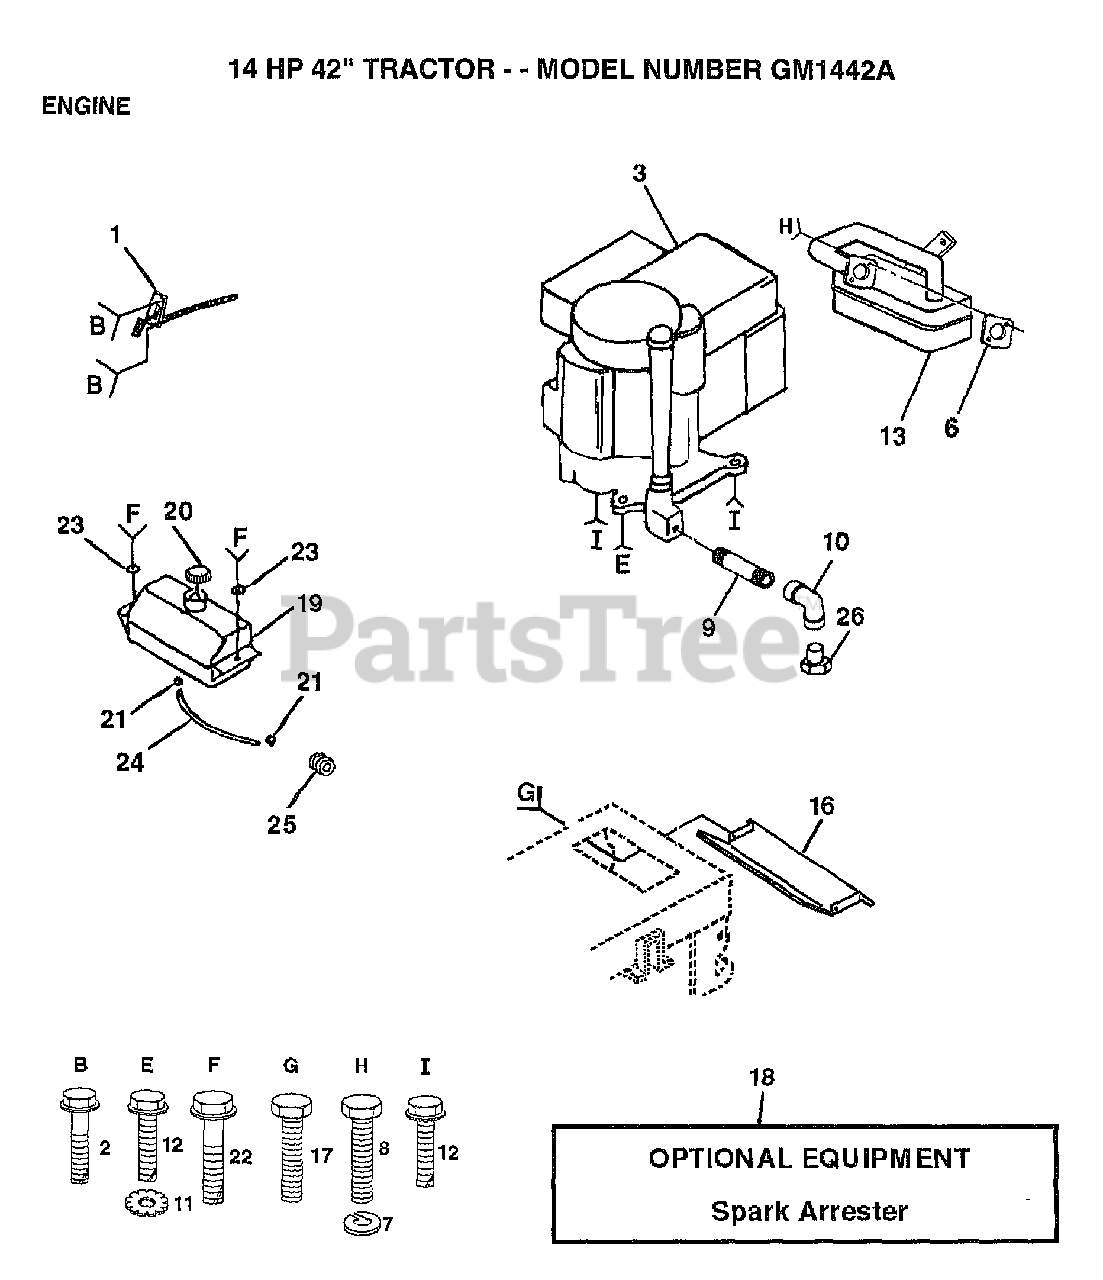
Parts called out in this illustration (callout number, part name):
1	THROTTLE CONTROL
2	SCREW LT
7	LOCKWASHER
8	SCREW
9	PIPE NIPPLE
10	ELBOW
11	LOCKWASHER
12	SCREW
13	MUFFLER
16	HEAT SHIELD
17	SCREW
19	TANK.FUEL.LT.
20	CAP ASM FUEL
21	HOSE CLAMP
22	SCREW HEX CRT
23	WASHER
24	LINE FUEL
